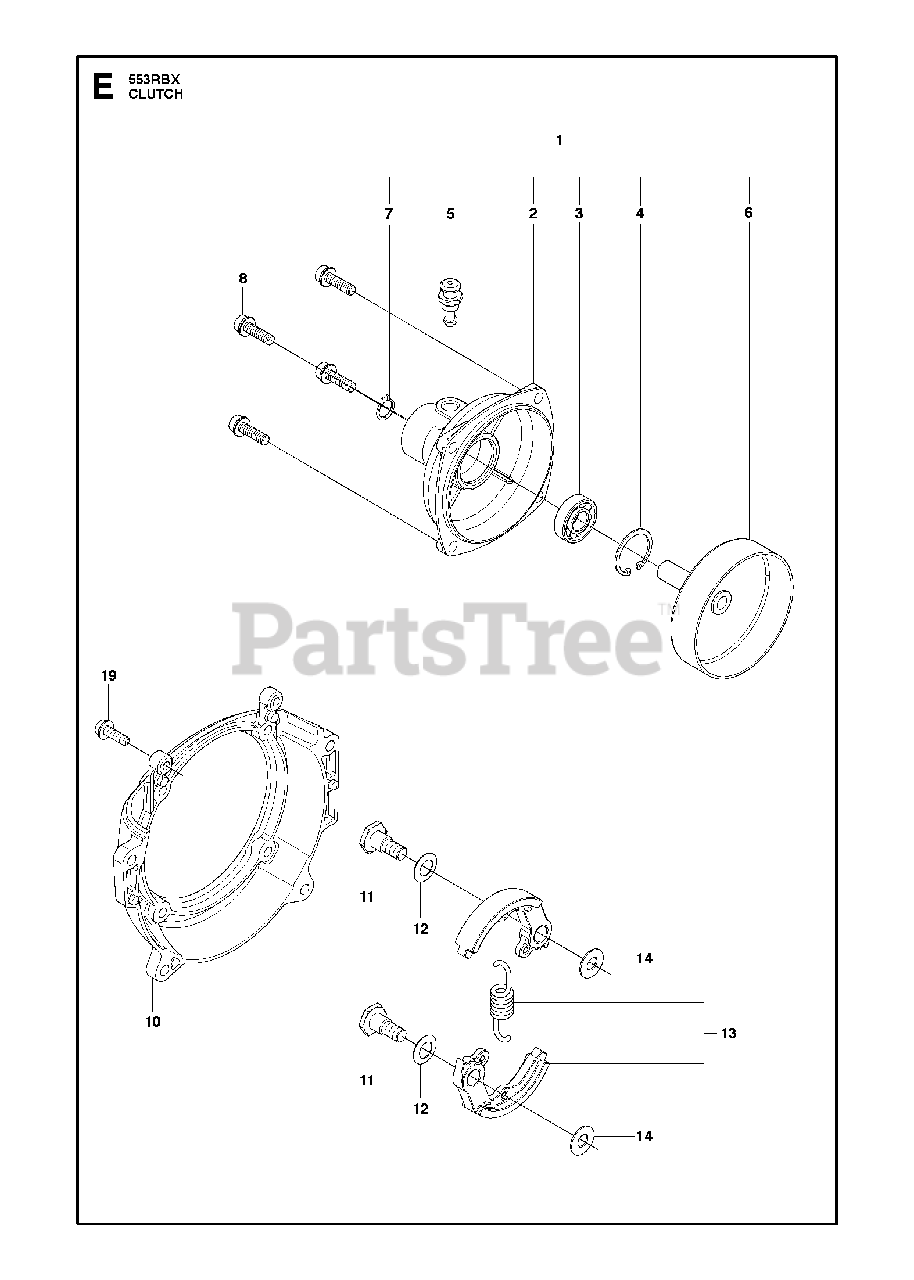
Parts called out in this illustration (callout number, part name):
3	BEARING
4	RING
6	DRUM
7	RING
19	BOLT
